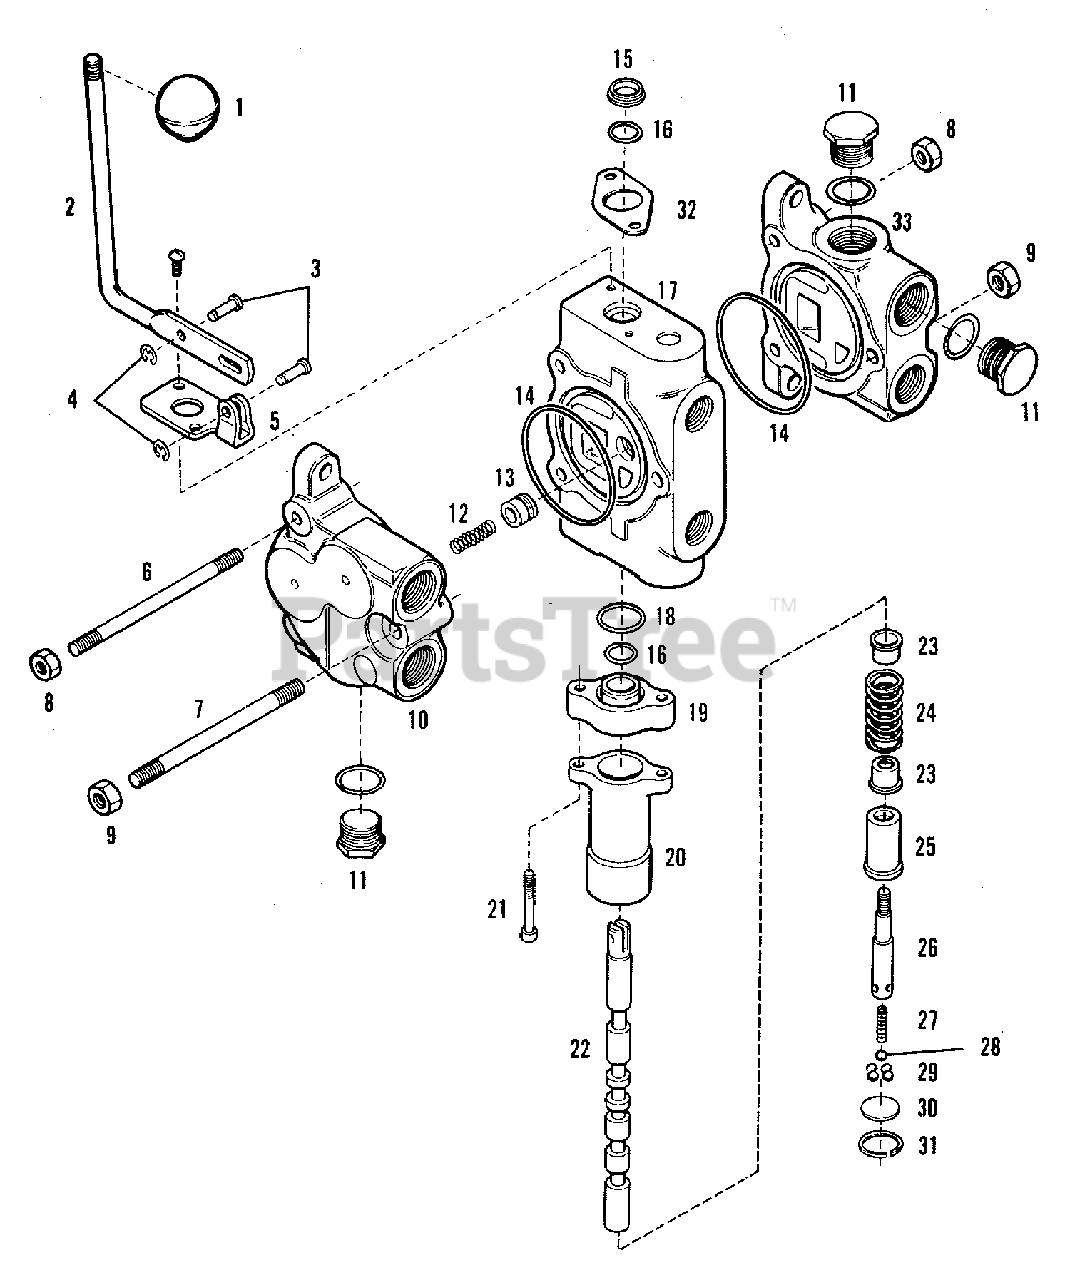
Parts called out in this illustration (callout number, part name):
5	BRACKET, Pivot
5	SCREW, Round Head, 1/4NC x 3/8
6	ROD, Tie, 5/16
7	ROD, Tie, 3/8
8	NUT, 5/16NC
10	HOUSING, Outlet Section
11	PLUG, Straight Thread, 7/8-14 (w/O-Ring)
14	O-RING, 2-15/64
15	WIPER, Seal
17	PLUNGER, Section Assembly
20	CAP, Plunger
21	CAPSCREW, Hex Socket Head, 1/4NC x 1-1/4
22	PLUNGER
23	SEAT, Spring
24	SPRING, Plunger
32	SEAL, Plate
33	INLET SECTION ASSEMBLY
